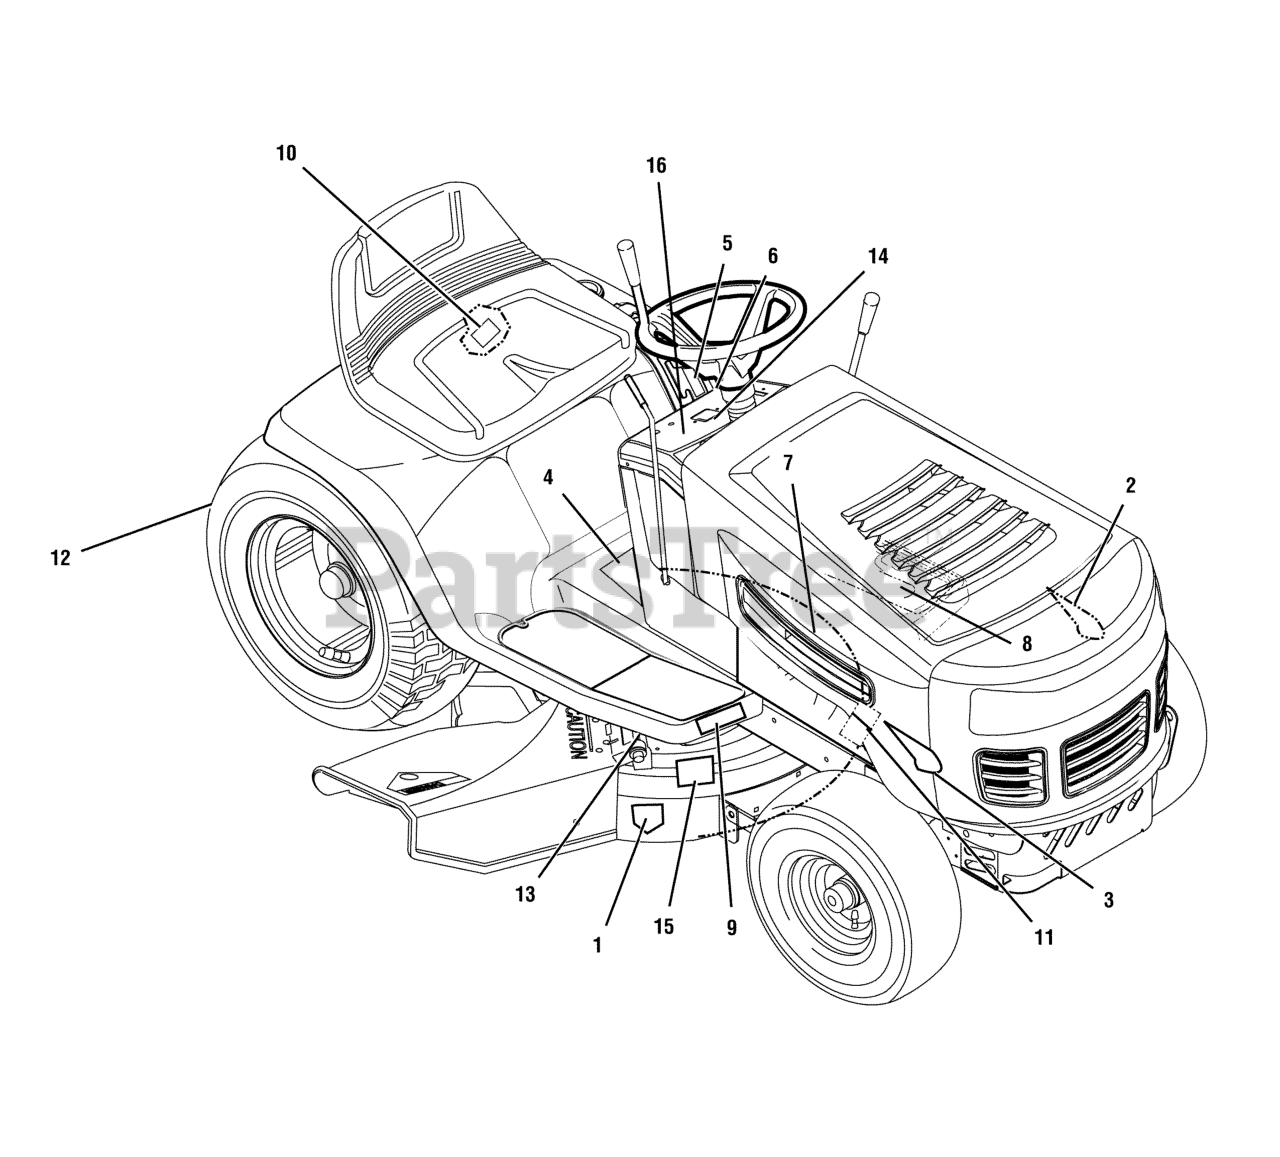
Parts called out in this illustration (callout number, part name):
1	DECAL, Cut Finger Symbols
2	DECAL, 135/102
3	DECAL, Murray
4	DECAL, Warning Export
5	DECAL, 7 Position Cut Height
6	DECAL, Deck Level
7	DECAL, No Step Export
8	DECAL, Brake/Clutch Export
9	DECAL, Hydro Drive
10	DECAL, Auto Drive Dump Valve
11	DECAL, Heat Shield Warning
12	DECAL, Warning Load Limit Export
13	DECAL, Warning Pinch Point
14	DECAL, Dash/Symbols W1
15	DECAL, 100db Export
16	DECAL, Gas Gauge
